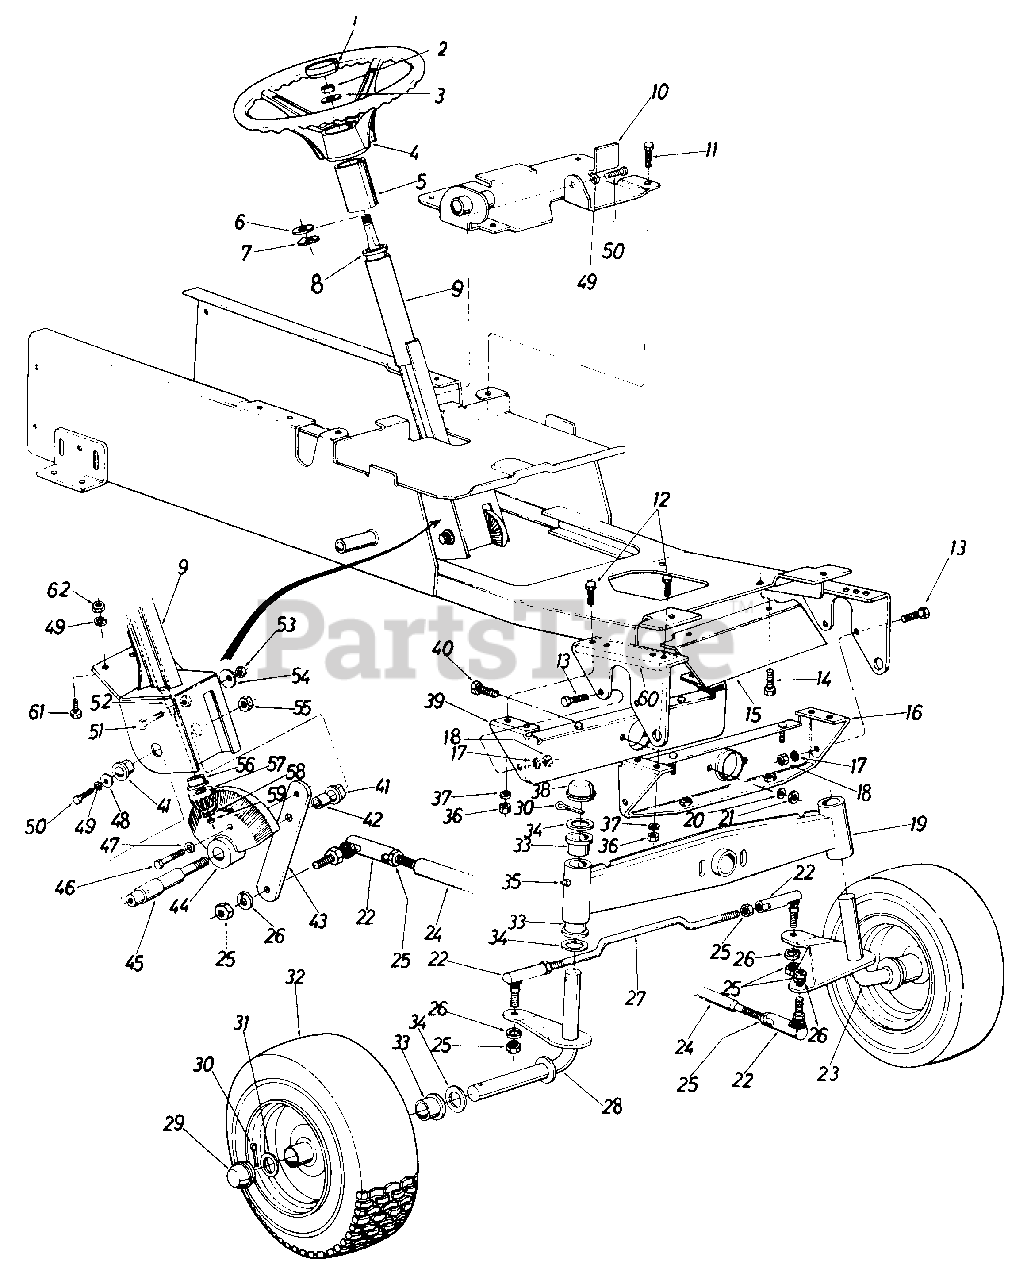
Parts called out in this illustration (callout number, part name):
1	Steering Wheel Cap
2	Hex Cent. L-Nut 5/16-18 Thd.
4	Steering Wheel
5	Steering Tube Outer
6	Double"D" Fl-Wash.
7	Wave Wash. .660 I.D. x .88 0 O.D.
8	Ball Brg. .63 I.D. x 1.38 O.D.
10	Dash Panel Base Plate Ass'y
11	Hex Self-Tap Scr. 3/8-16 x .75" Lg.
12	Hex Scr. 3/8-16 x 1.50" Lg.*
13	Hex Scr. 3/8-16 x 1.00" Lg.
14	Hex Wash. S.F. Tap Scr. 3/8-16 x 1.25" Lg.
15	Dust Shield
18	Hex Nut 3/8-16 Thd.
19	Pivot Bar Ass'y.
20	Bell-Wash. 3/8" Scr.*
21	Hex Cent. L-Nut 3/8-16 Thd.
22	Drag Link End
23	Axle Ass'y. L.H.
25	Hex Nut 1/2-20 Thd.
26	L-Wash. 1/2" Scr.
28	Axle Ass'y. R.H.
30	Cotter Pin 3/16" Dia. x 1.50" Lg.
31	Fl-Wash. 1.00" I.D. x 1.62" O.D.
33	Flange Brg. 1.00" I.D.
34	Fl-Wash. 1.00" I.D. x 1.62" O.D.
35	Grease Fitting
36	Hex Nut 3/8-16 Thd.
37	L-Wash. 3/8" Scr.*
38	Dust Cover
40	Hex Scr. 3/8-16 x 2.50" Lg.
41	Flange Brg. w/ Flats .753 I.D.
42	Steering Gear Shaft Spacer
43	Steering Arm
44	Bevel Gear
45	Steering Gear Shaft
46	Hex Scr. 3/8-16 x 1.50" Lg.
47	L-Wash. 3/8" Scr.
48	Fl-Wash. .406 I.D. x 1.25" O.D.
49	L-Wash. 3/8" Scr.
50	Hex Scr. 3/8-16 x .75" Lg.
51	Nylon Hex Scr. 3/8-16 x 1.25" Lg.
52	Steering Shaft
53	Hex Jam Nut 3/8-16 Thd.
54	Bell-Wash. .400 I.D. x 1.13 O.D.
55	Hex Ins. L-Nut 1/2-20 Thd.
56	Hex Flange Brg. .630 I.D.
57	Pinion Gear
58	Fl-Wash. 3/8" Dia.
59	Hex Cent. L-Nut 5/16-24 Thd.
62	Hex Nut 3/8-24 Thd.
